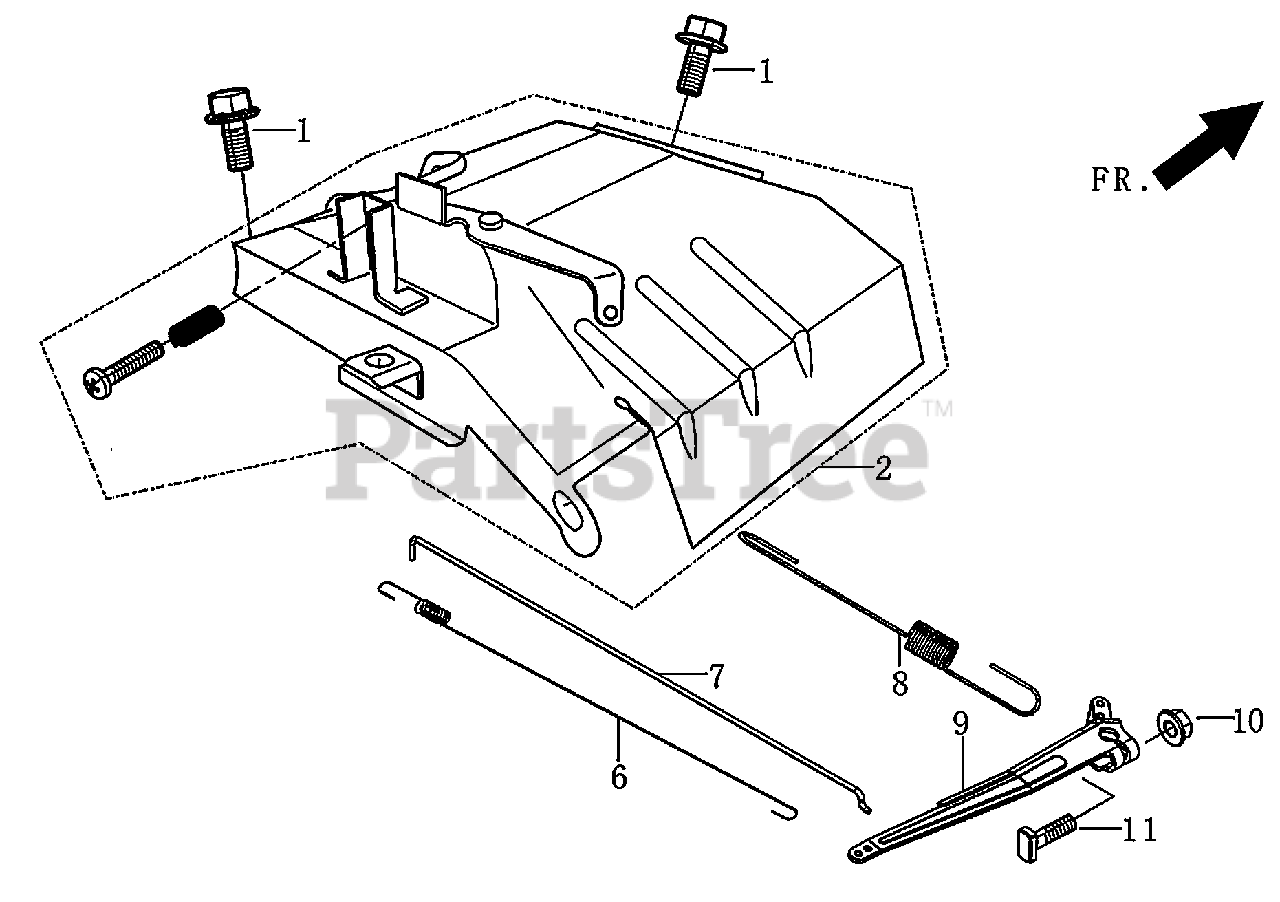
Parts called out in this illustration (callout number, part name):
2	CONTROL ASSY, THROTTLE
6	SPRING, THROTTLE RETURN
7	ROD, GOVERNEOR
8	SPRING, GOVERNOR
9	SUPPORT, GOVERNOR ARM
11	BOLT, GOVERNOR SUPPORT
